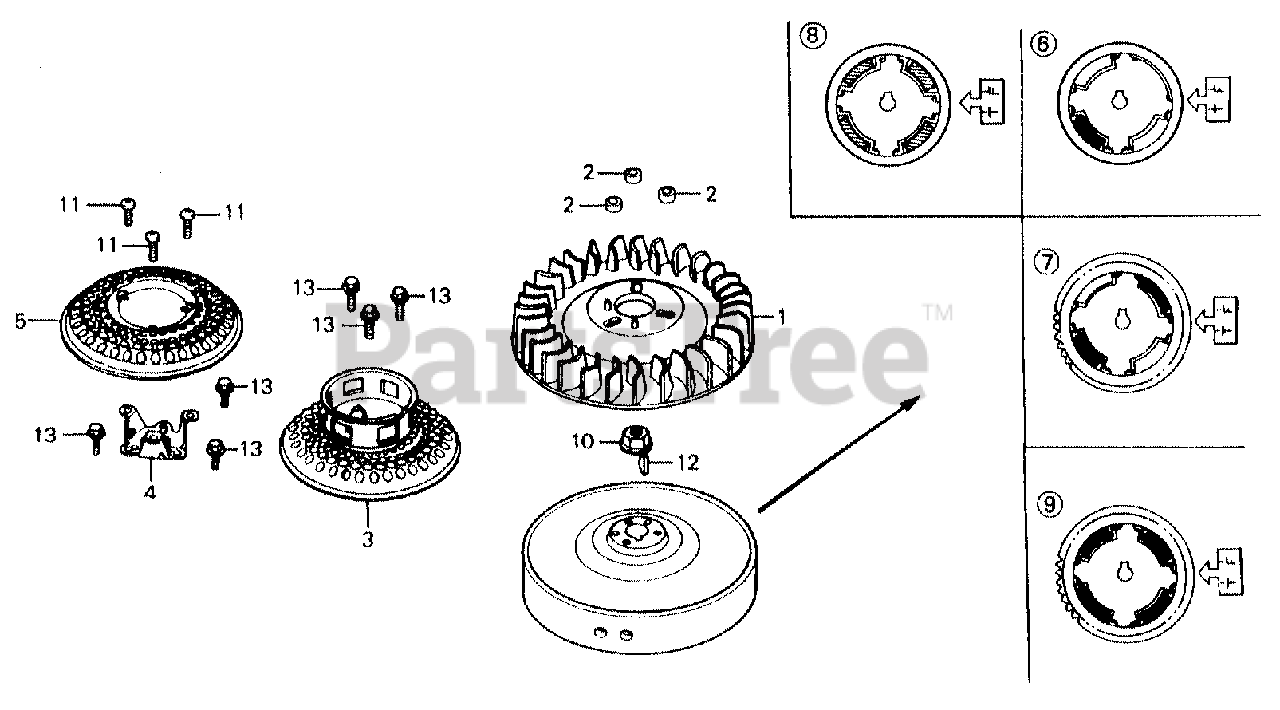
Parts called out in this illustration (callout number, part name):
1	FAN, COOLING
2	COLLAR, FAN
4	HOLDER, SCREEN GRID
5	GRID, SCREEN
9	FLYWHEEL
10	NUT, SPECIAL (16MM)
11	SCREW, PAN (5X8)
12	KEY, SPECIAL WOODRUFF (25X18)
13	BOLT, FLANGE (6X16)
